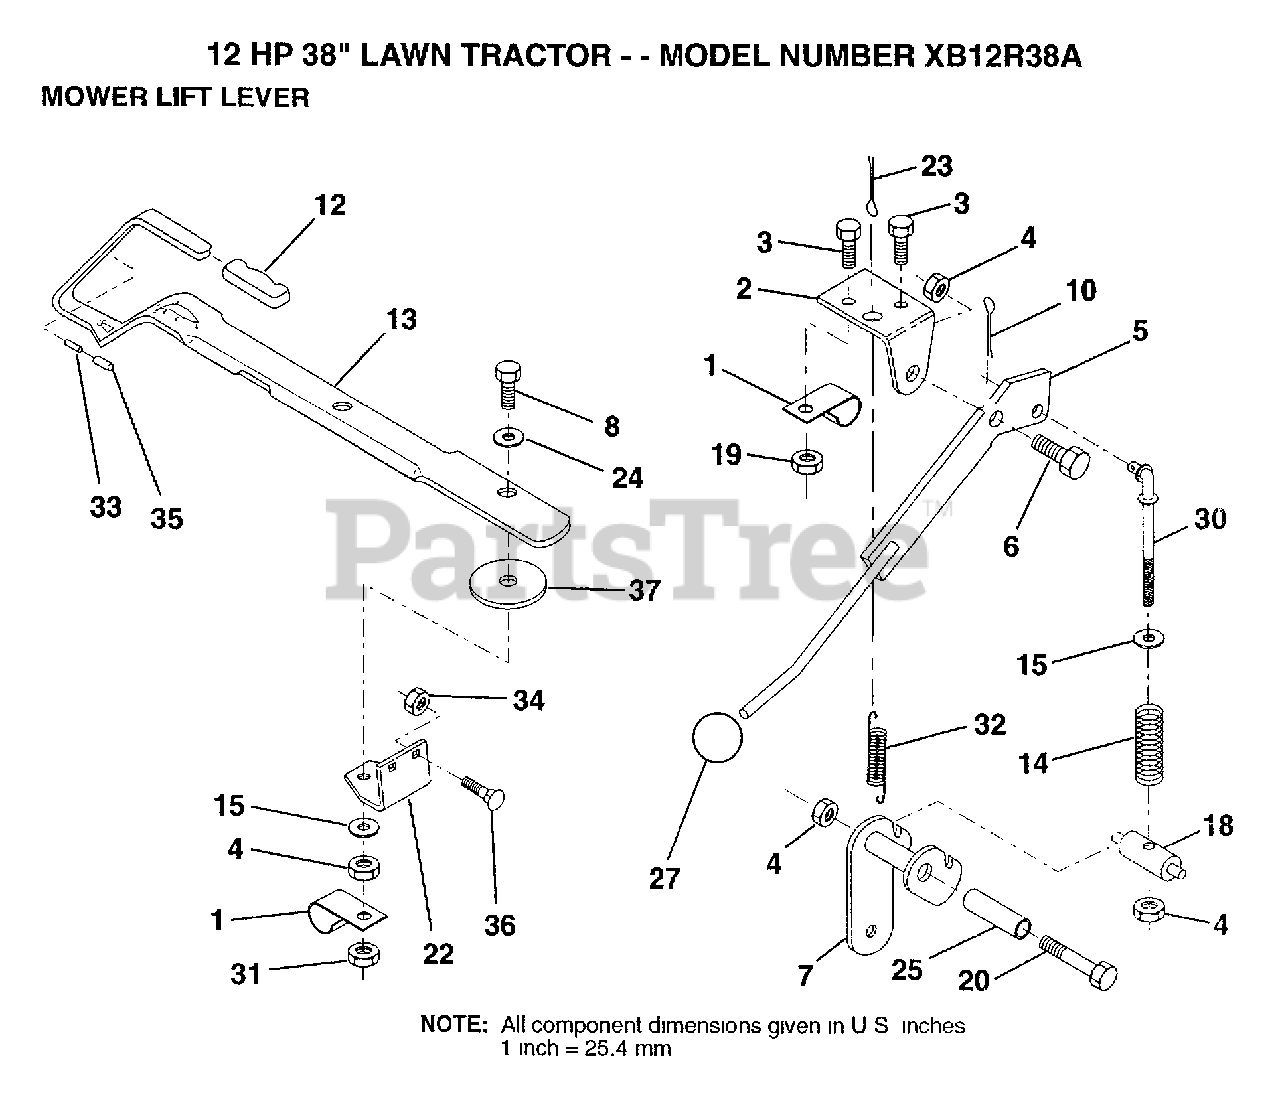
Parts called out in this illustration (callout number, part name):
1	"CLIP,INSULATOR"
2	BRKT CLUTCH
3	BOLT
5	CLUTCH LEVER AS
6	"BOLT, SHOULDER LT"
7	MWR CLUT ARM ASM
8	BOLT
10	COTTER PIN
12	LIFT LEVER HANDLE
13	LIFT HANDLE ASM
14	COMP CLUTCH SPRNG
15	WASHER HYT
18	TRUNNION
20	BOLT
22	LIFT LEVER BRKT
24	WASHER
25	TUBE SPACER
27	KNOB
30	ROD TENSION CLUTC
31	LOCKNUT
32	SPRING EXT
35	VINYL CAP RED
36	BOLT
37	WASHER T
